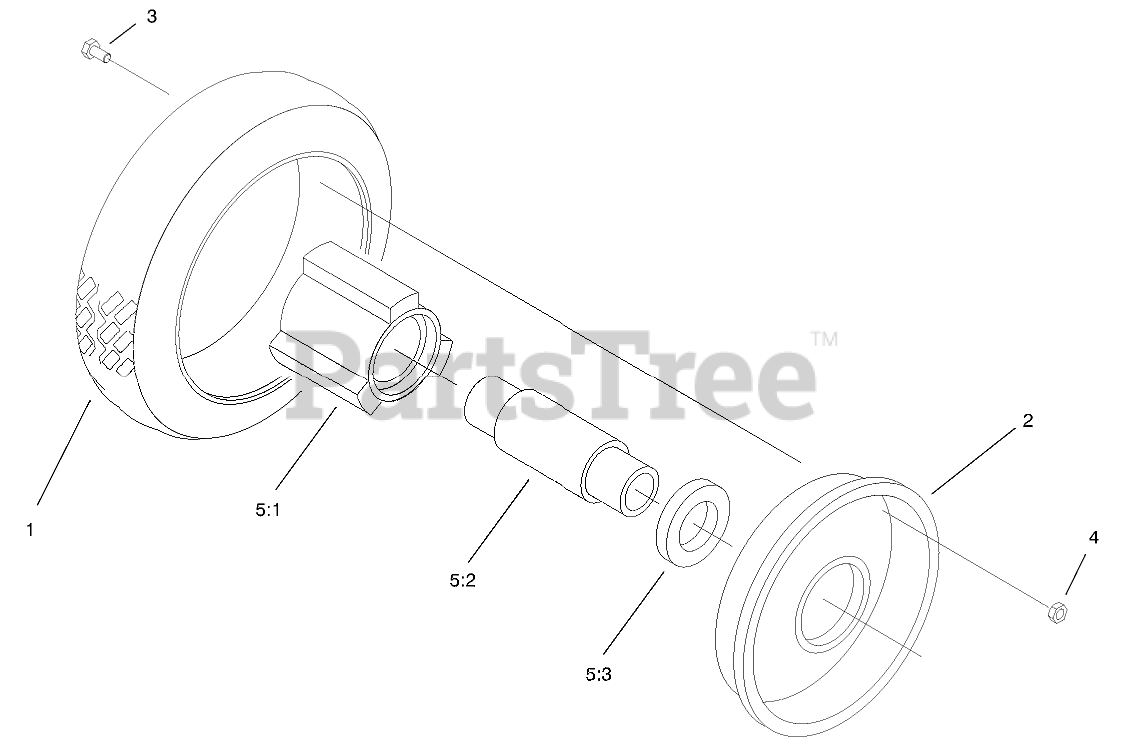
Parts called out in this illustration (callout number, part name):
2	PLATE-WHEEL, HALF
3	SCREW-HH
4	NUT-LOCK, NI
5	HUB and BEARING ASM
5:1	HUB-BEARING
5:2	SPACER-BEARING
5:3	BEARING-WHEEL
